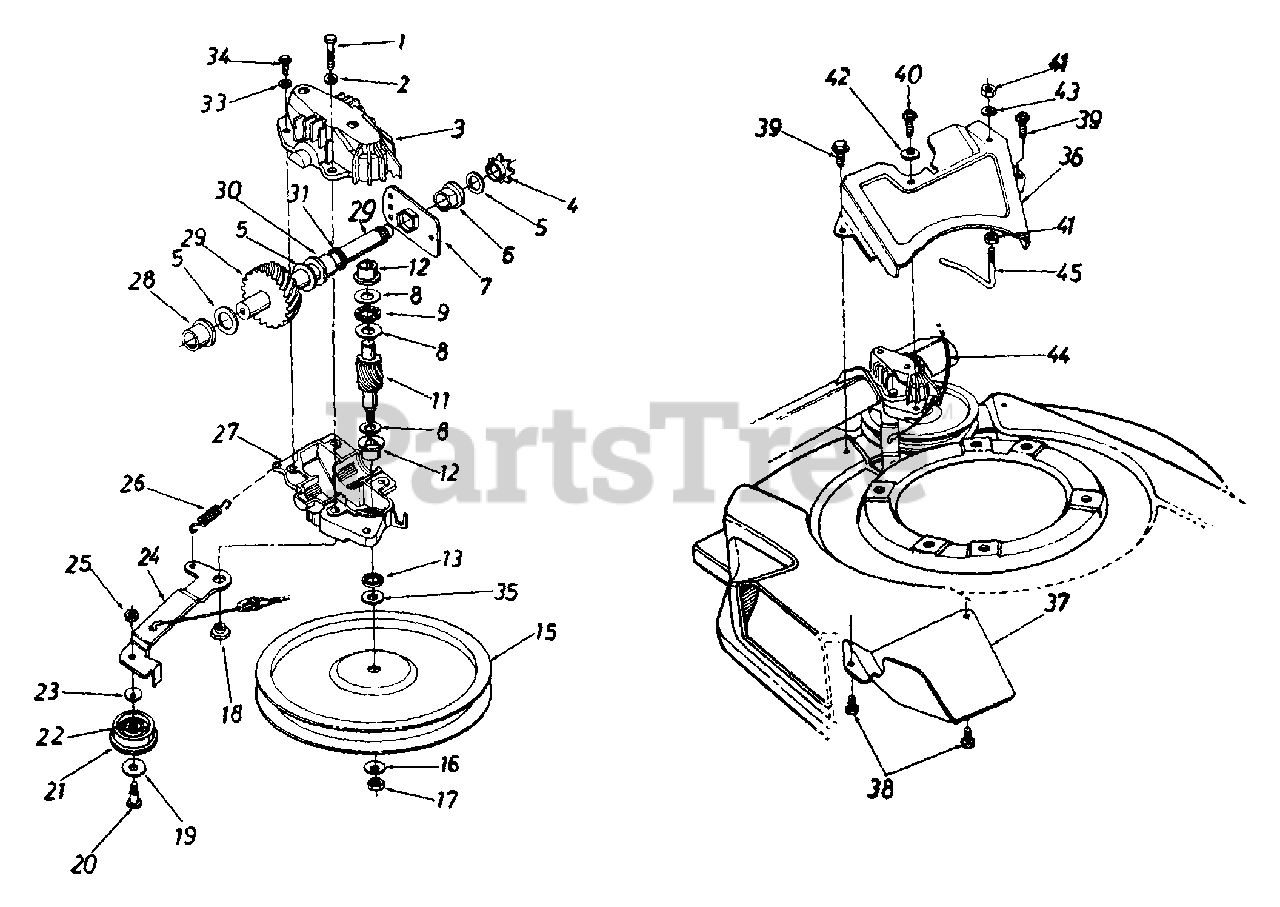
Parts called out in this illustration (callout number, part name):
1	Hex Patch Bolt 1/4-20 x 1.25" Lg.
2	L-Wash. 1/4" I.D.
3	Upper Hsg. Half
4	#48 Sprocket 7 Tooth x 1/2 Pitch
5	Fl-Wash. 5/8" I.D. x .030
6	Hex Flange Brg. .631" I.D.
8	Thrust Wash. .382" I.D. x .70" O.D.
9	Thrust Bearing .375" I.D. x .812" O.D.
11	11 Tooth Helical Gear
12	Flange Bearing
15	Fl-Pulley 5.06" I.D.
16	Bell-Wash. .265" I.D. x .75"
17	Hex Nut 1/4-28 L.H. Thd.
18	Shld. Spacer .375" Dia. x .170
19	Fl-Wash. .390" I.D. x 1.0"
20	Shld. Bolt .375" Dia. x .40"
21	Fl-Idler Plastic 1.50" Dia.
22	Needle Brg. .375" x .375"
23	Bell-Wash. .265" I.D. x .75"
24	Idler Brk't. Ass'y.
25	Hex Patch L-Nut 1/4-28 Thd.
26	Extension Spring 1.12" Lg.
27	Lower Hsg. Half
28	Flange Bearing .56 Dia.
29	Sprocket Shaft Ass'y.
30	Flange Bearing .629 Dia.
31	Oil Seal .625 Dia.
33	L-Wash. #10 I.D.
34	Hex B-Tap Scr. #10 x .62"
35	Hex Washer .26" x .88"
39	Hex AB-Tap Scr. 1/4 x .50" Lg.
40	Hex B-Tap Scr. 1/4 x .62" Lg.
41	Hex Nut 1/4-20 Thd.
42	Bell-Wash. .265" I.D. x .75"
43	L-Wash. 1/4" I.D.
44	S.P. Cable - 48" Lg.
45	S.P. Belt Guard
